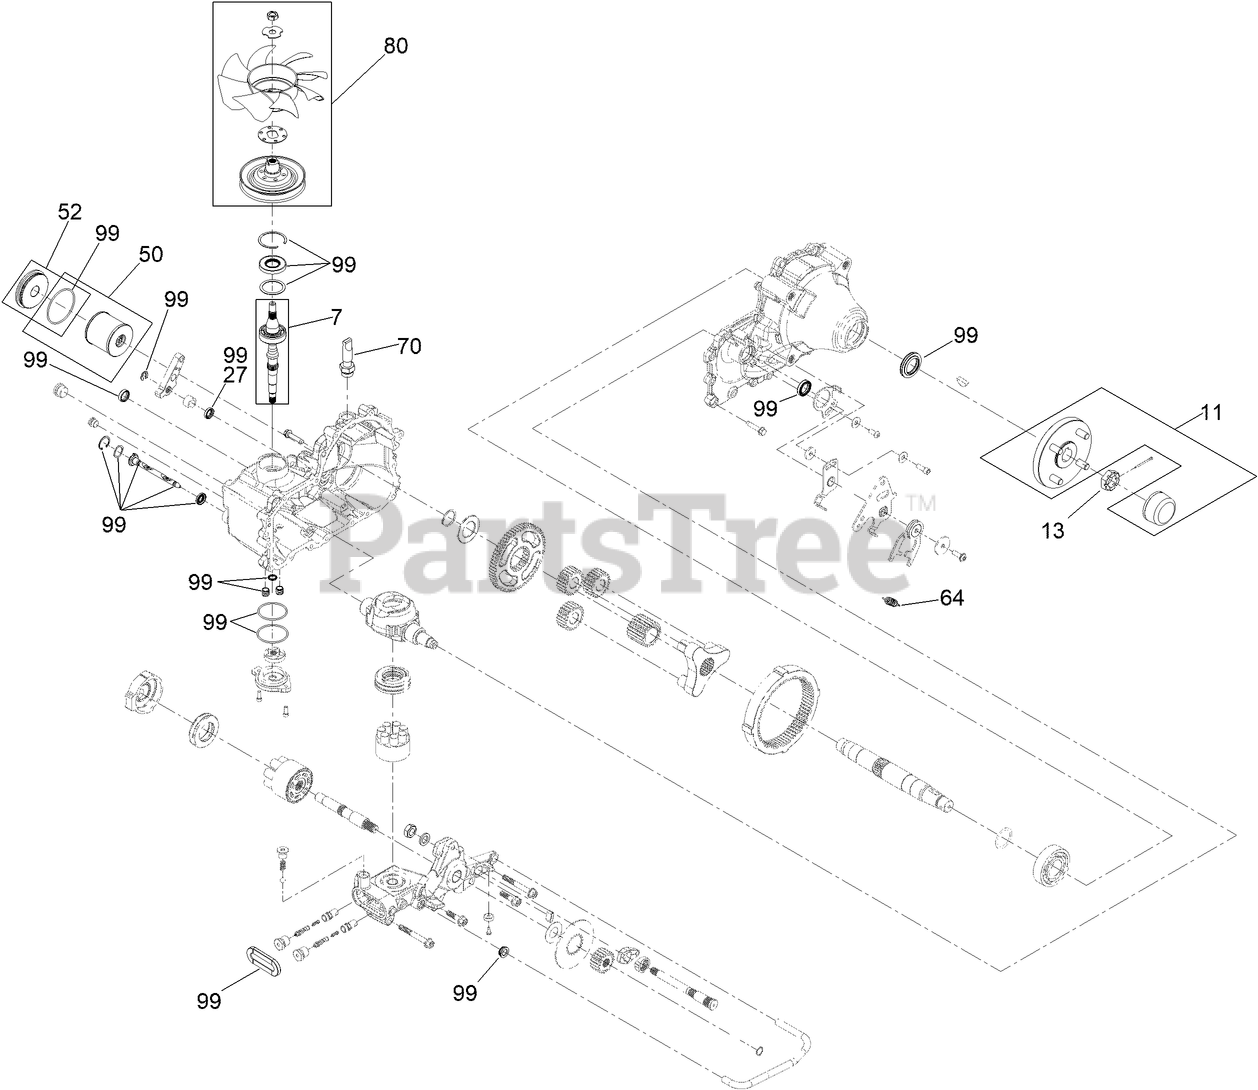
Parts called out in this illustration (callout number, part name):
7	KIT, INPUT SHAFT
11	HUB-4 BOLT
13	NUT, SLOTTED
27	SEAL, LIP-BRAKE
50	KIT, FILTER
52	KIT, FILTER PLUG
64	SPRING-EXTENSION
70	FITTING-5/8 BEADED, 7/8 SAE
80	KIT, FAN AND PULLEY
99	KIT-OVERHAUL SEAL
